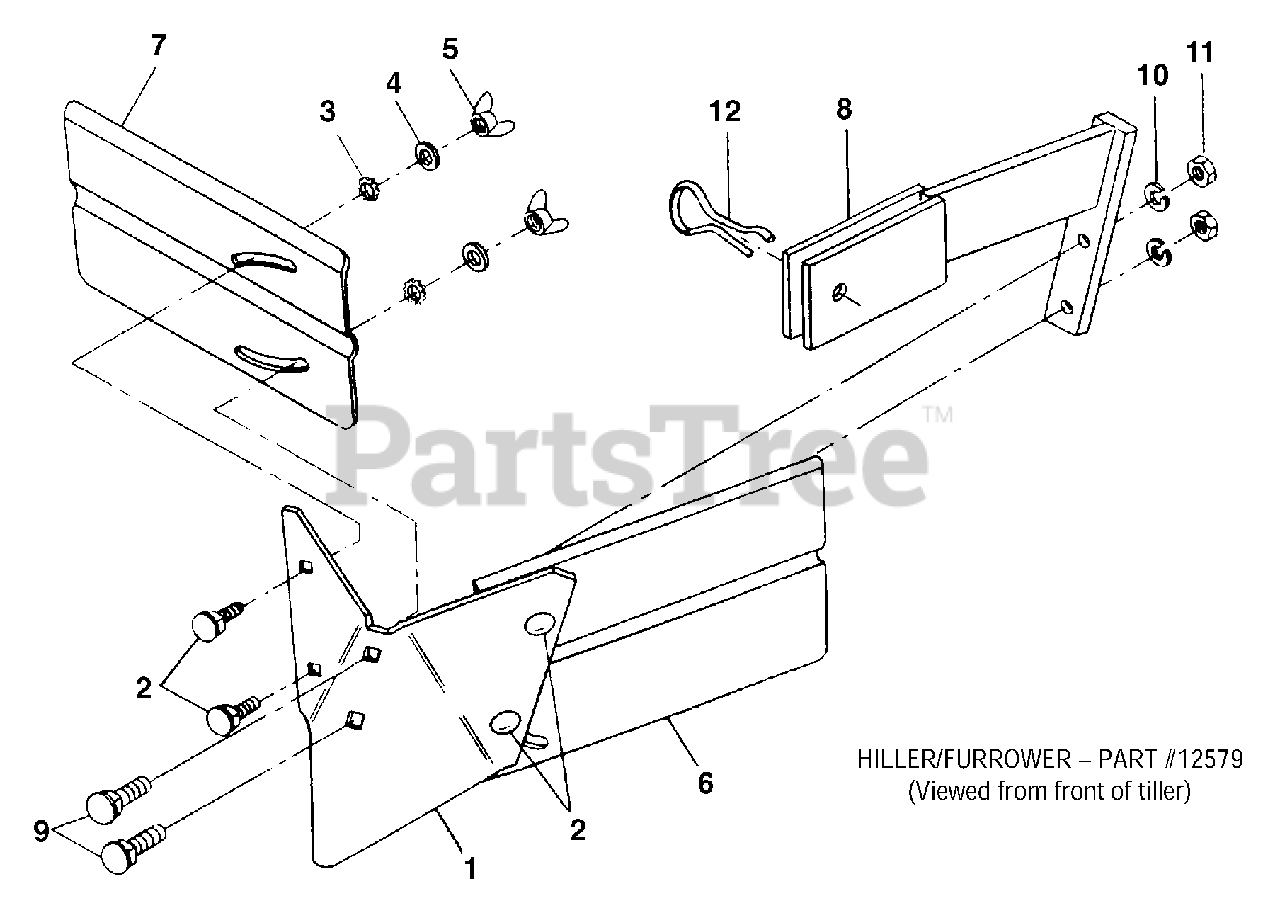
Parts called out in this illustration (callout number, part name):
1	Furrower Blade
2	Carriage Bolt, 5/16-18 x 3/4
3	Star Washer, External Tooth, 5/16
4	Plain Washer, 5/16 S.A.E
5	Wing Nut, 5/16-18
6	Hiller Wing, left
7	Hiller Wing, right
8	Blade Mounting Bracket
9	Carriage Bolt, 3/8-16 x 1-1/2
10	Lockwasher, 3/8, plated
11	Hex Nut, 3/8-16, plated
12	Clinch Pin
12579	Complete Hiller/Furrower Attachment
